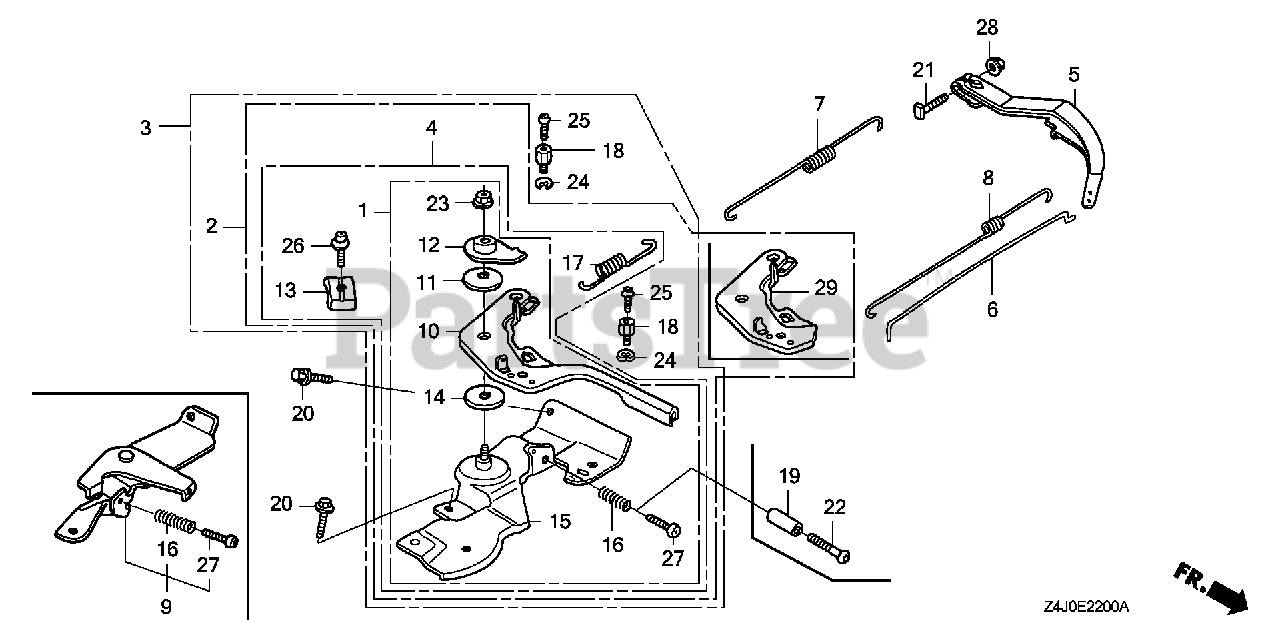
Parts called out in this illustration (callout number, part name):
4	CONTROL ASSY. (REMOTE)
5	ARM, GOVERNOR
6	ROD, GOVERNOR
7	SPRING, GOVERNOR
8	SPRING, THROTTLE RETURN
10	LEVER, CONTROL
11	SPRING, LEVER
12	WASHER, CONTROL LEVER
13	HOLDER, CABLE
14	SPACER, CONTROL LEVER
15	BASE, CONTROL (REMOTE)
16	SPRING, CONTROL ADJUSTING
17	SPRING, CABLE RETURN
19	COLLAR, STOPPER
20	BOLT, FLANGE (6X12) (CT200)
21	BOLT, GOVERNOR ARM
22	SCREW, RECESSED (5X25)
23	NUT, SELF-LOCK (6MM)
26	SCREW, PAN (5X16)
27	SCREW, PAN (5X25)
28	NUT, FLANGE (6MM)
